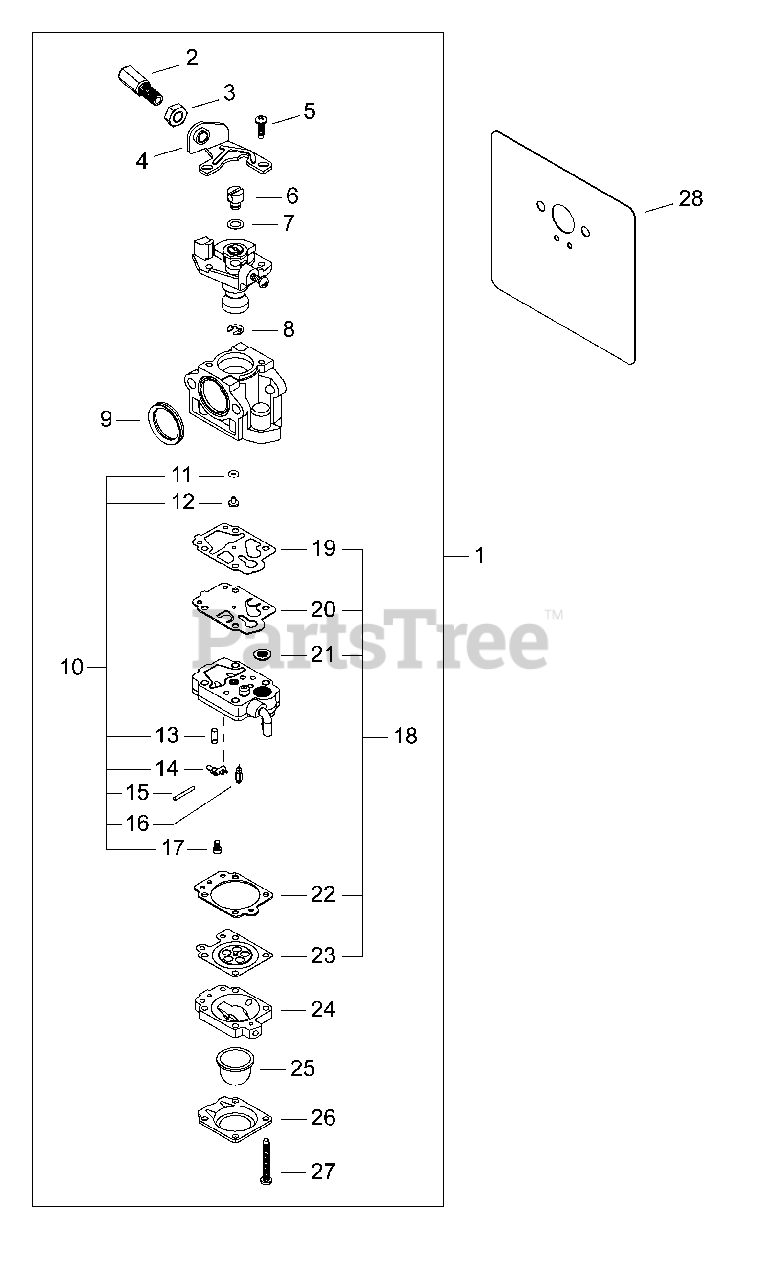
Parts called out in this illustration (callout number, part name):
1	CARBURETOR
2	NUT, CABLE ADJUST
3	NUT
4	BRACKET, CABLE
5	SCREW
6	SWIVEL
7	WASHER
8	RING, RETAINING
9	SEAL
10	INLET NEEDLE VALVE KIT
11	O-RING
12	JET, MAIN
13	SPRING, METERING LEVER
14	LEVER, METERING
15	PIN, METERING LEVER
16	VALVE, INLET NEEDLE
17	SCREW, METERING LEVER PIN
18	DIAPHRAGM/GASKET KIT
19	GASKET, PUMP
20	DIAPHRAGM, PUMP
21	STRAINER
22	GASKET, METERING
23	DIAPHRAGM, METERING
24	BASE, PURGE
25	BULB, PURGE
26	RETAINER, PURGE BULB
27	SCREW, PUMP COVER
28	GASKET, INTAKE
